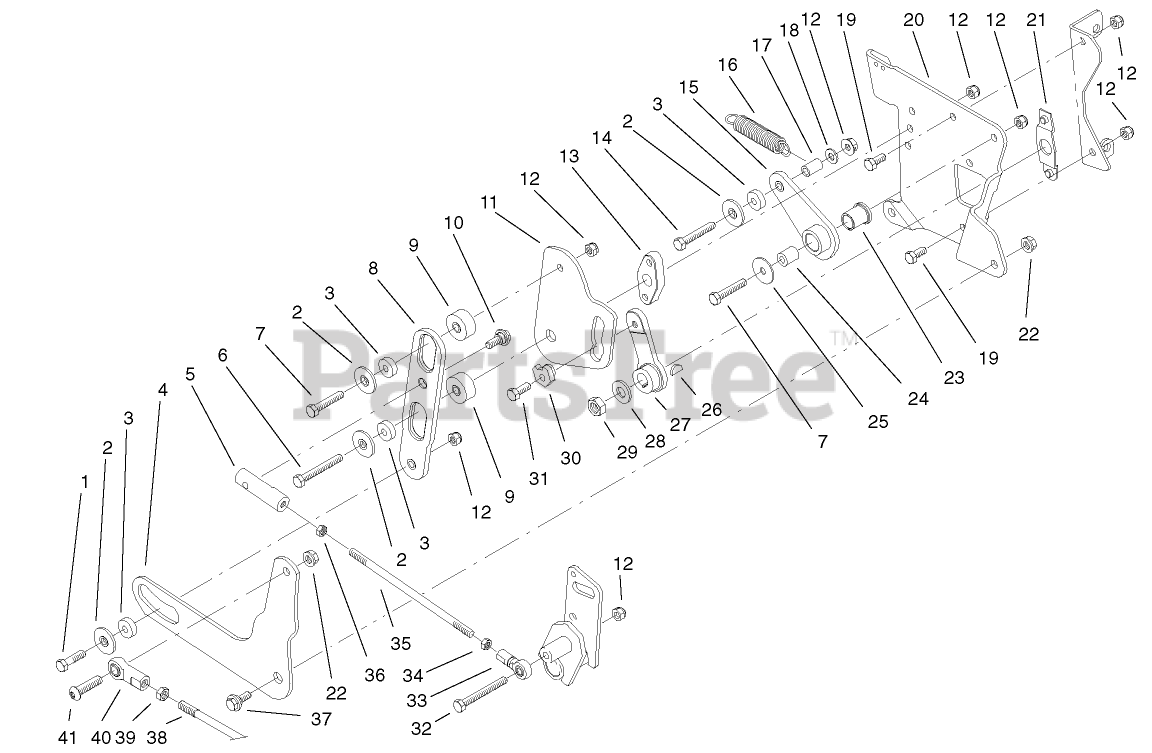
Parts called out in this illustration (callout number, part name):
1	SCREW-HH
2	RETAINER-BEARING
3	BEARING-BALL
4	SLIDER-LIFT
5	END-ROD, RH
6	SCREW-HH
7	SCREW-HH
8	SLIDER-CONTROL, SPEED
9	STANDOFF-CAM PLATE
10	BOLT-SHOULDER
11	PLATE-CAM
12	NUT-LOCK, NI
13	STANDOFF-SLIDER
14	SCREW-HH
15	ARM-RETURN TO NEUTRAL
16	SPRING-IDLER
17	STANDOFF-SPRING
18	WASHER-PLAIN
19	SCREW-HH
20	PLATE-CONTROL
21	LOCATOR-CONTROL PLATE
22	NUT-HEX
23	BUSHING-FLANGED
24	SPACER
25	WASHER-FLAT
26	KEY-WOODRUFF
27	ARM-CONTROL, SPEED
28	WASHER-FLAT
29	NUT-HEX
31	SCREW-THREAD LOCKING
32	SCREW-HH
33	END-ROD, RH
34	NUT-JAM
35	ROD-SLIDER TO PIVOT
36	NUT-JAM
37	BOLT-SHOULDER
38	ROD-LIFT
39	NUT-HJ
40	END-ROD, FEMALE
41	SCREW-HSBH
